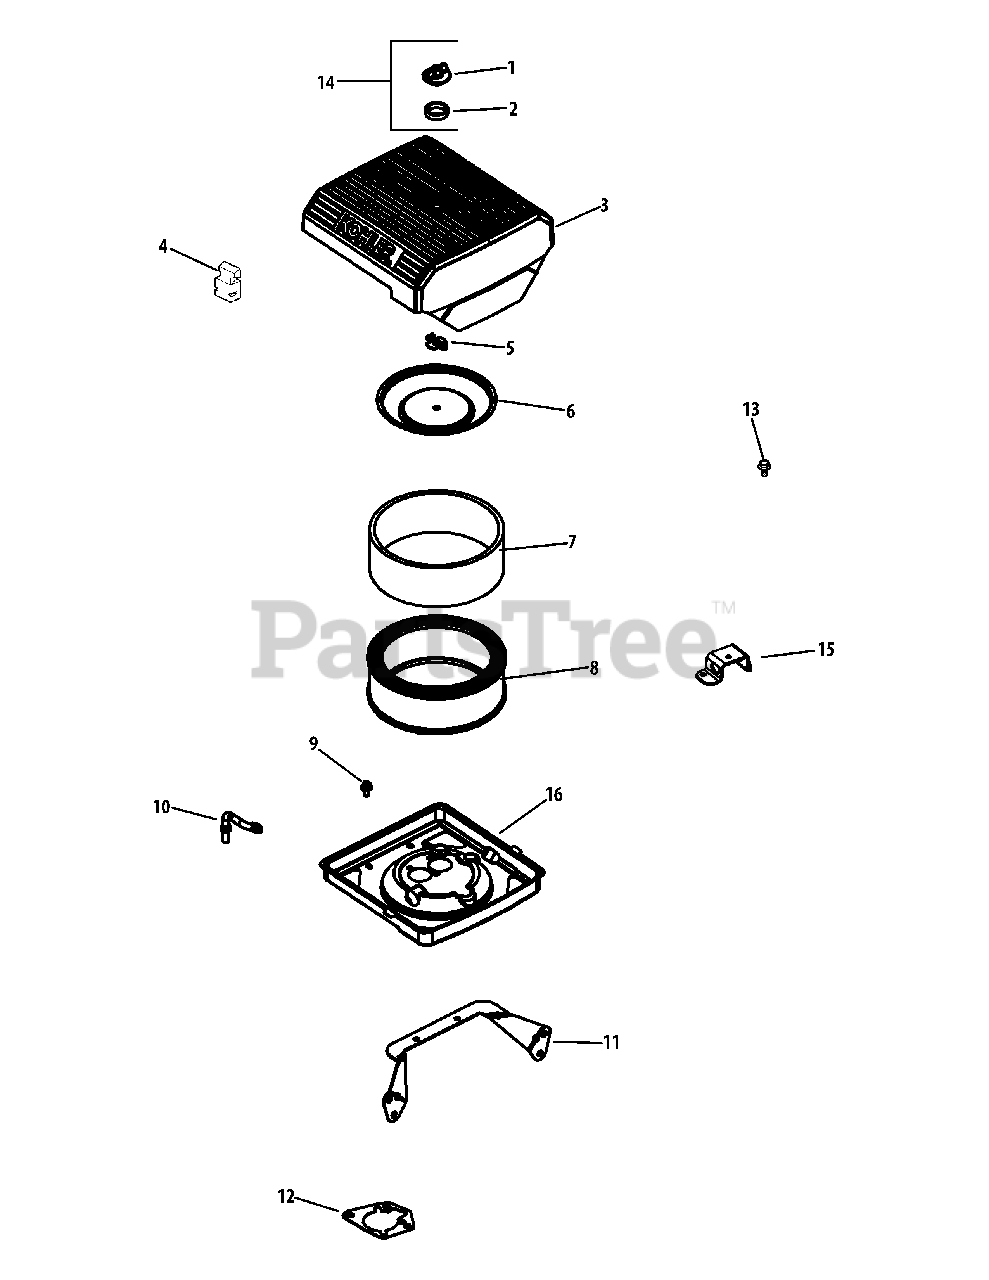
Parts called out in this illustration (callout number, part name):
4	Inner Air Cleaner Seal
6	Inner Air Cleaner Cover
7	Pre-cleaner Element (Low)
8	Air Cleaner Element
9	Evaporative Hose Connector
11	Air Cleaner Base Bracket
12	Air Cleaner Base Gasket
13	Thread Forming Screw
14	Knob Kit w/ Seal
15	Air Cleaner Bracket
16	Air Cleaner Base Kit
